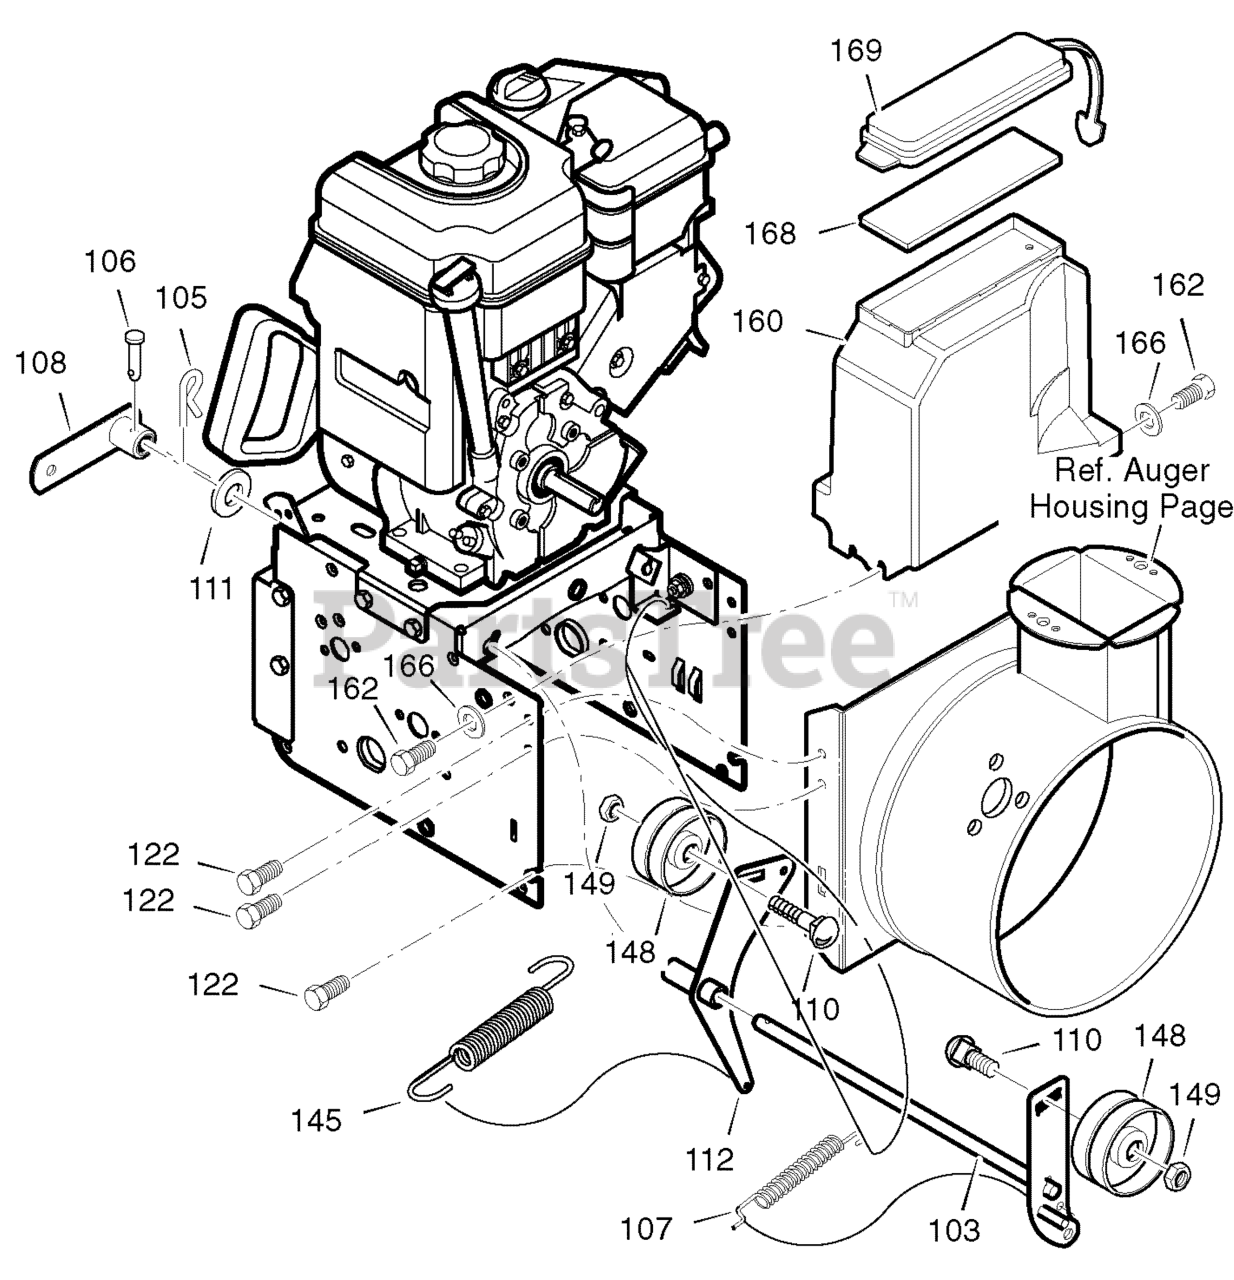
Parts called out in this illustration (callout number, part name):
103	ASSY, AUGER IDLER
105	PIN, HAIR
106	PIN, CLEVIS 3/16" DIA
107	SPRING, TENSION
108	SPRING ATTACHMENT
110	BOLT, 3/8-16X1.25
111	WASHER, FLAT
112	BRACKET, IDLER
122	SCREW, 5/16-18 x 0.50
145	SPRING, CLUTCH
148	PULLEY, IDLER
149	NUT, JAM 3/8-16
160	COVER, BELT
162	SCREW, 1/4-20 X .63
166	WASHER, FLAT
168	PAD, FOAM
